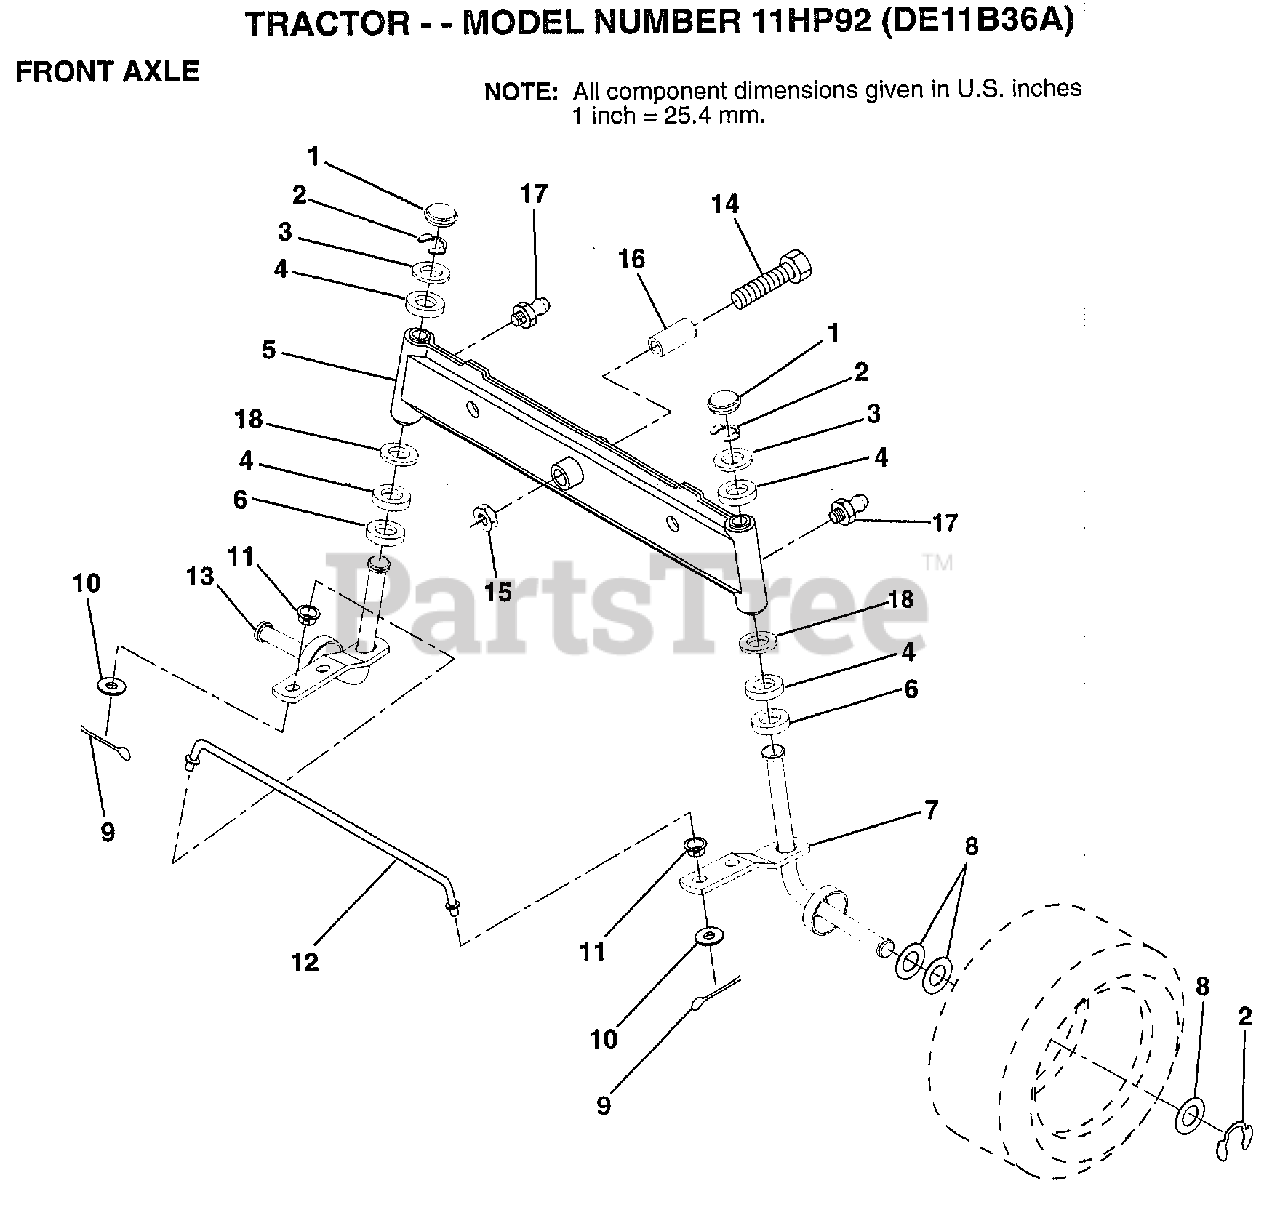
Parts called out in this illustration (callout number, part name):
1	CAP
2	RING
3	WASHER
4	COL. SRTG. BEAR.
5	AXLE ASM FRONT
6	WASHER .T
7	SPINDLE.ASSY.RH
8	WASHER
9	COTTER PIN
10	WASHER
11	BUSHING.DRAGLINK
12	TIE ROD
13	SPINDLE.ASSY.LH
14	BOLT HEX 5/8-11
15	"NUT-LOC,FLANGE LT"
16	BEARING
17	ZERK M
18	WASHER
